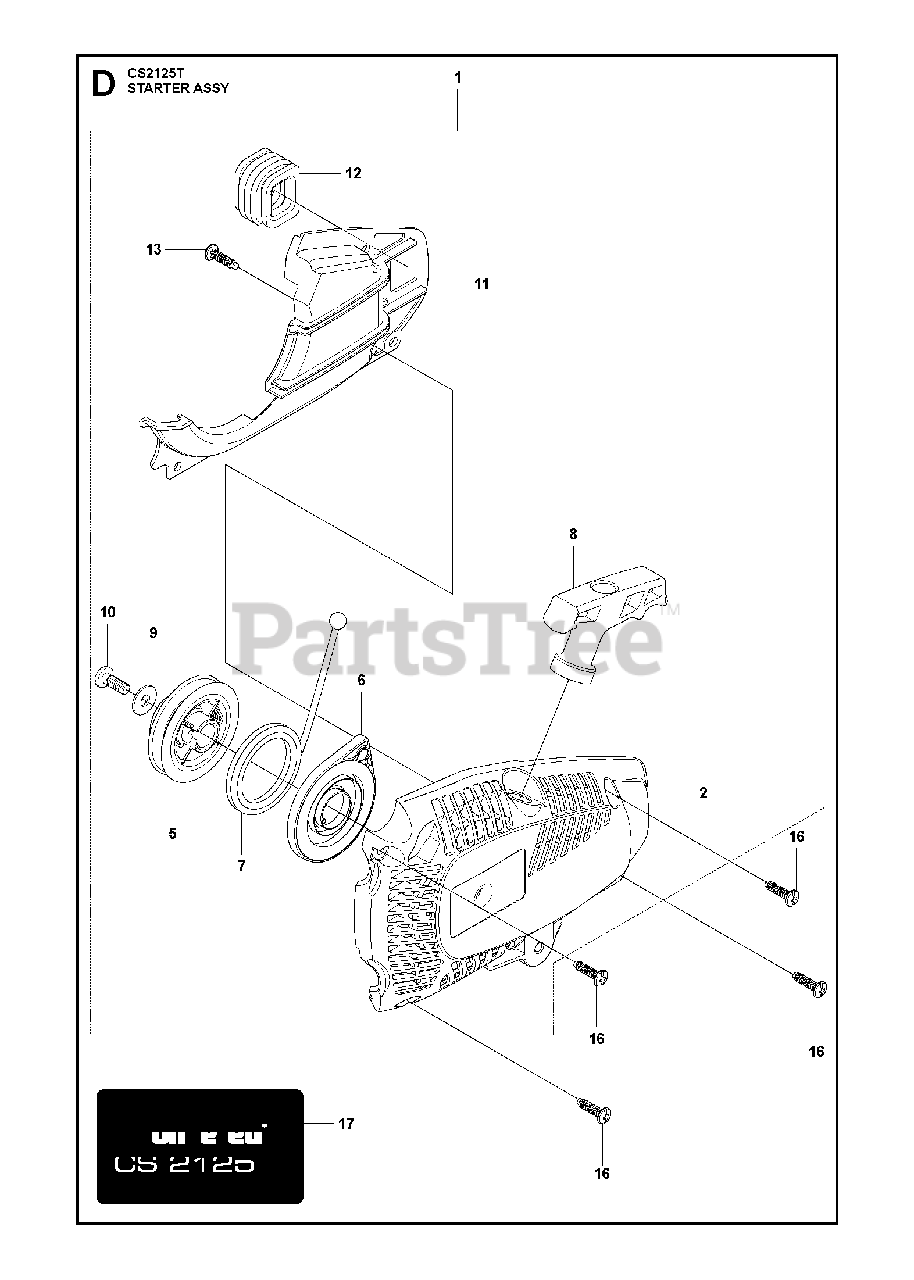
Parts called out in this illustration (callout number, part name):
8	KNOB
9	WASHER
13	SCREW
